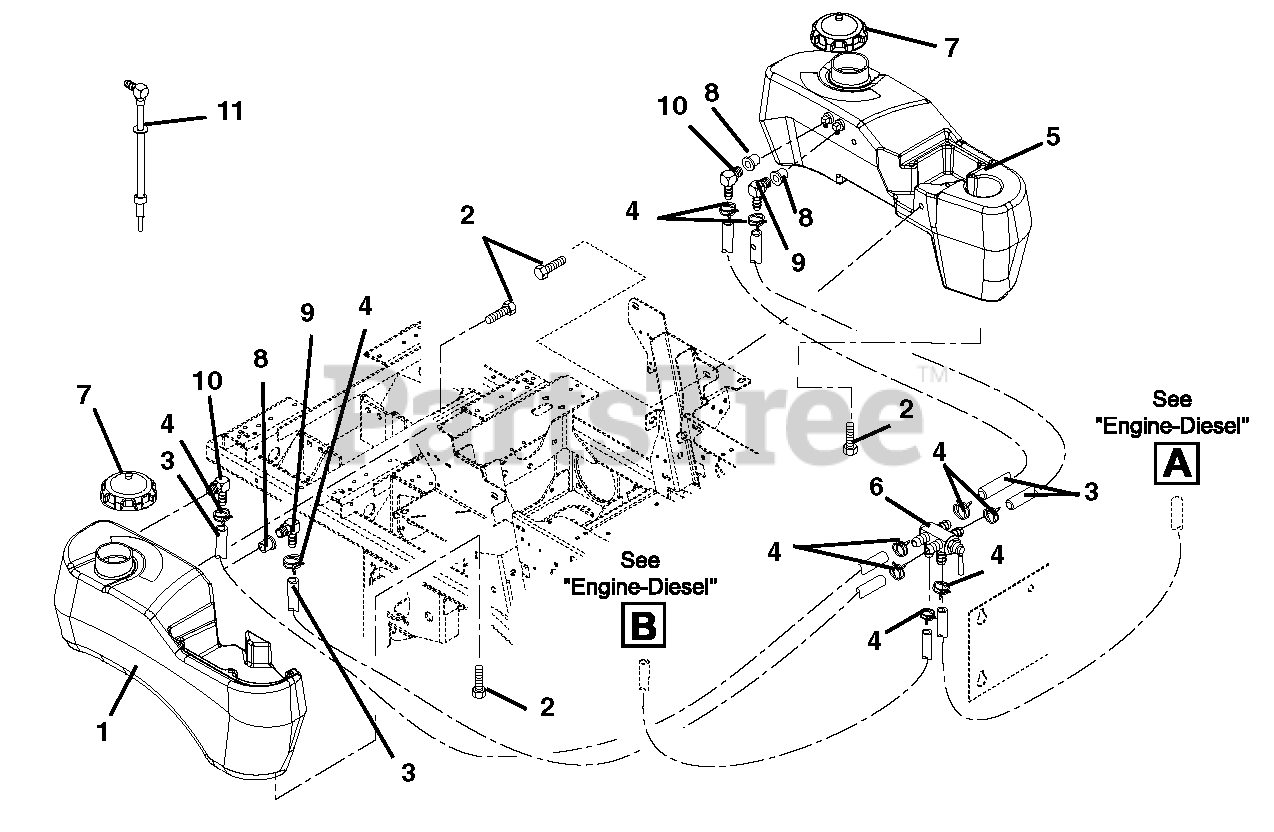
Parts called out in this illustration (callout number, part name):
1	Tank, Right Hand Fuel
2	Bolt, SEMS .31-18 x .62
3	Hose, .31 ID
4	Clamp, Hose Wire .52/.55
5	Tank, Left Hand Fuel
6	Valve, Fuel
7	Cap, Fuel
9	Fitting, Tank
10	Fitting, Tank
11	26" Fuel Line Kit – Diesel (Inside Tank)
